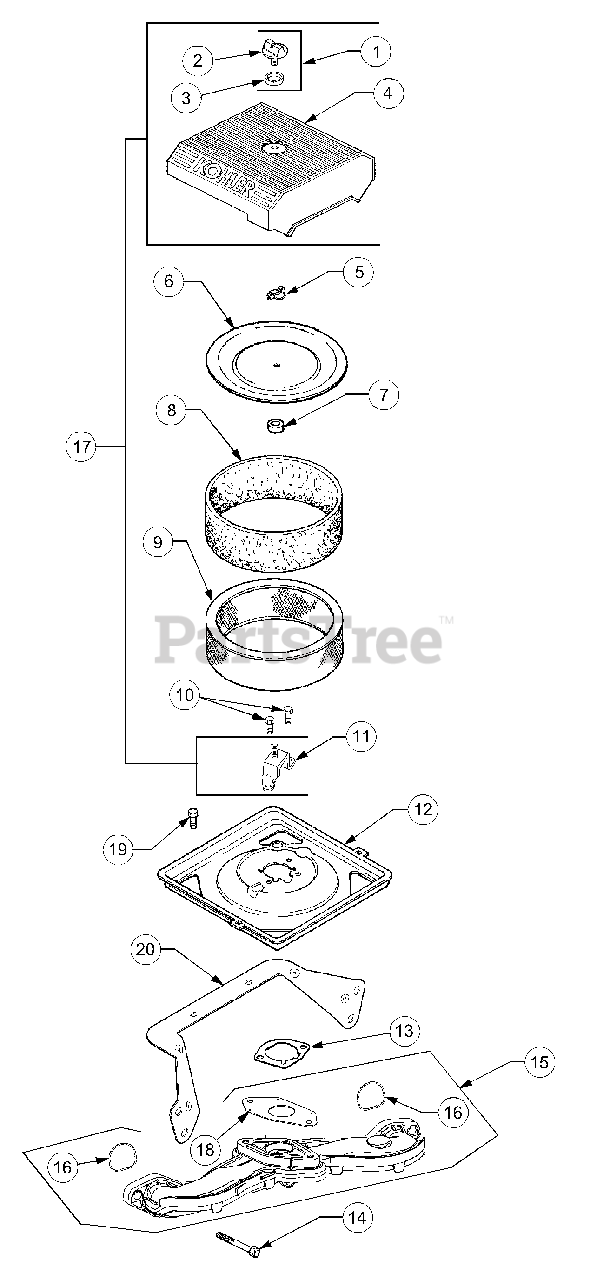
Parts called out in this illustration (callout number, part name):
1	Kit, Knob w/Seal
3	Seal, Air Cleaner Cover Knob
4	Cover, Air Cleaner
6	Cover, Inner Air Cleaner
7	Seal, Inner Air Cleaner
8	Precleaner, Element
9	Element, Air Cleaner
10	Screw, Hex Flange, M6 x 1.0 x 16
11	Bracket, Air Cleaner Base
12	Base, Air Cleaner
13	Gasket, Air Cleaner Base
14	Screw, Hex Flange, M6 x 1.0 x 40
15	Manifold, Intake
16	O-Ring, Intake Manifold
17	Kit, Air Cleaner Cover
18	Gasket, Carburetor
19	Screw, Hex Flng, M5 x 0.8 x 10
20	Bracket, Air Cleaner Base
